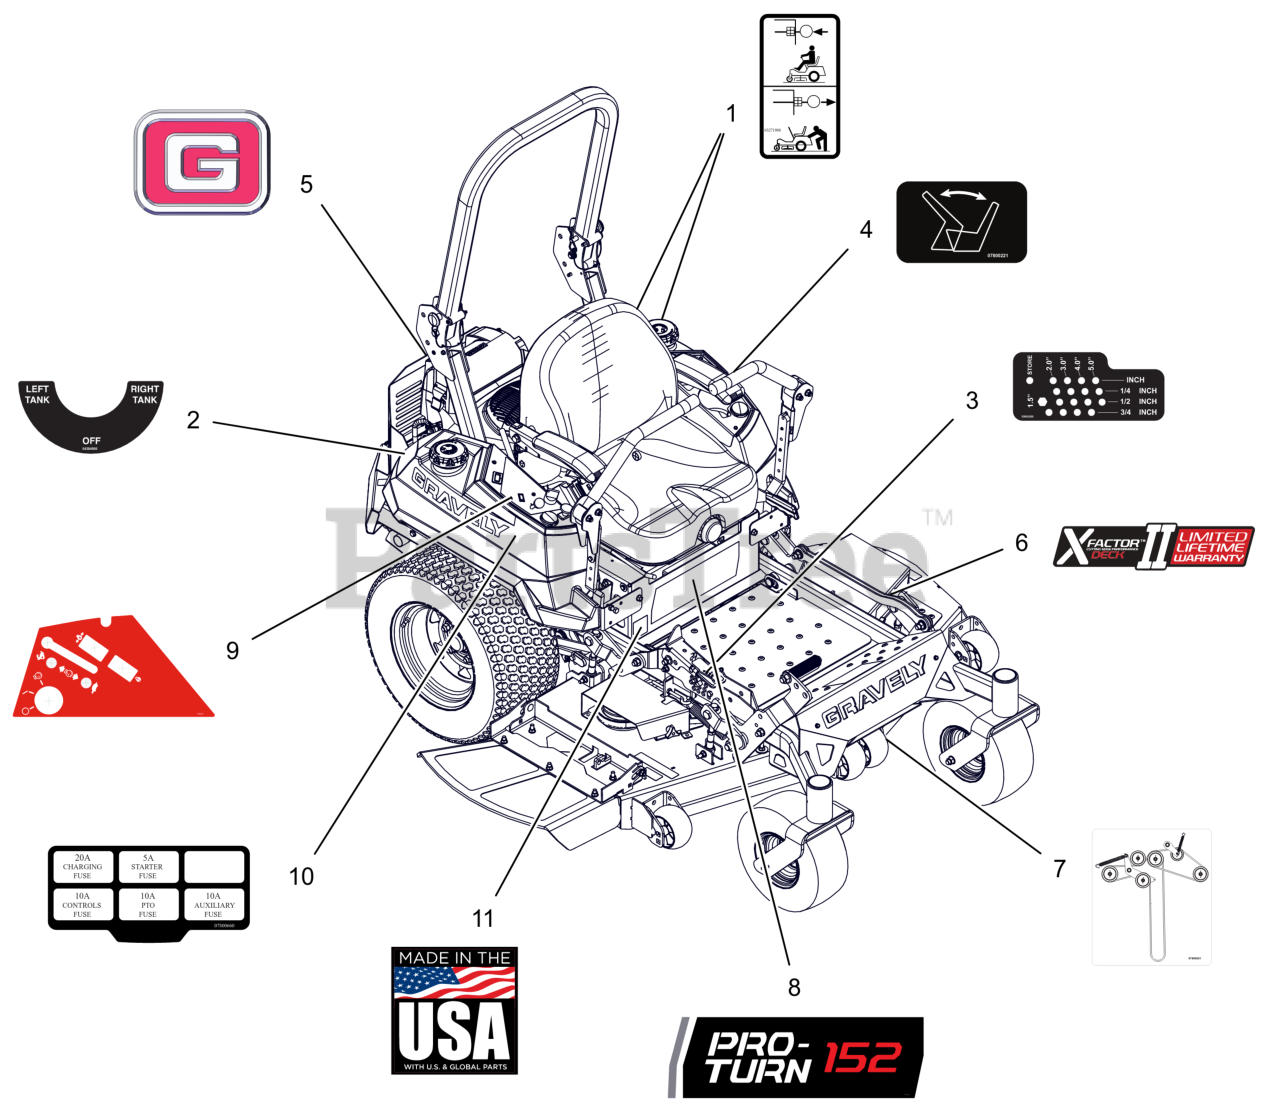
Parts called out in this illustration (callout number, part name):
1	DECAL, TRANSMISSION DISCONNECT
2	DECAL, FUEL VALVE
3	DECAL, HEIGHT OF CUT
4	DECAL - SEAT RELEASE
5	DECAL, GRAVELY BRAND
6	DECAL, X-FACTOR DECK
7	DCL,BELT ROUTE-RH V-SIDE IDLER
8	DECAL, PRO-TURN 152
9	DECAL, EFI CONTROL PANEL
10	DECAL, FUSE BLOCK
11	DECAL, MADE IN USA
